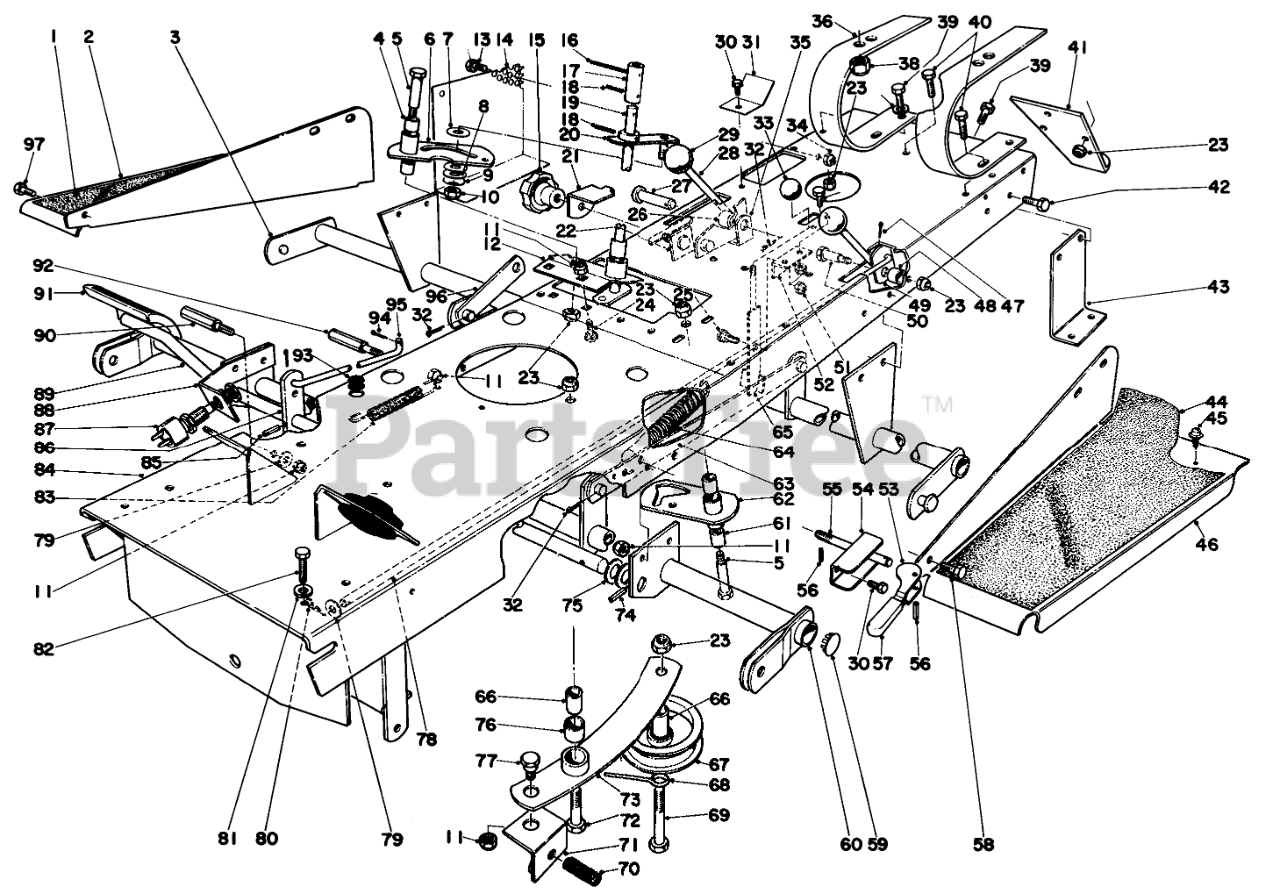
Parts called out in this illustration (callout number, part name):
1	Pad R. H.
2	Footrest R.H.
3	Cross Tube
4	BUSHING
5	Shoulder Bolt
6	Cam Plate
7	Washer
8	WASHER-FLAT
9	WASHER-SPRING
10	NUT-LOCK, NI
11	NUT-LOCK, CONE
12	Bracket-Control
13	SCREW-HH
14	Fan Guide Side
16	Roll Pin
17	Sleeve Handle
18	PIN-SPRING
19	Handle Hydro Control
20	Control Crank
21	Slide
22	Knob Plate
23	NUT-LOCK, CONE
24	BOLT-CARR
25	Shoulder Bolt
26	Spacer
28	Lever
29	Knob
30	SCREW-HWH
31	Shield Fan
32	PIN-COTTER
34	NUT-LOCK, CONE
35	Support Height of Cut Lever
36	Seat Spring
37	SCREW-HH
38	1/2-13 CONELOCK NUT
39	SCREW-HH
40	Capscrew
41	Hitch
42	SCREW-HH
43	Axle Support L.H.
44	Pad Left
45	10-16 X 3/8 THDG SCREW
46	Footrest
47	PIN-COTTER
48	Spacer
49	Lever
50	Shoulder Bolt
51	NUT-LOCK, CONE
52	Bracket Pivot
53	Idler Crank
54	Retainer Idler
55	Adjustment Rod
56	PIN-ROLL
57	Handle Grip
58	SCREW-HH
59	Plug Button
60	Cross Tube Front
61	BUSHING
62	Plate Neutralizer
63	Lift Equalizer
64	Spring Counterbalance
65	Drive Lever
66	Idler Spacer
67	Flat Idler
68	Belt Retainer
69	SCREW-HH
70	Compression Spring
71	Swivel Bracket
72	SCREW-HH
73	Bracket Idler
74	PIN-SPRING
75	WASHER-FLAT
76	.503ID X .875LG BSHG
77	Shoulder Bolt
78	Rod Clutch
79	WASHER-FLAT
80	PIN-COTTER
81	WASHER-LOCK
82	He Ha. Screw
83	Spring
84	Frame
85	PIN-ROLL
86	Pedal Crank Neutralizer
87	Switch Spno
88	Bracket Switch
89	Pedal
90	Pedal Stop
91	PAD-BRAKE
92	Brake Stop
93	GROMMET
94	PIN-COTTER
95	Link Neutralizer
96	Lift Link
97	SCREW-HH
